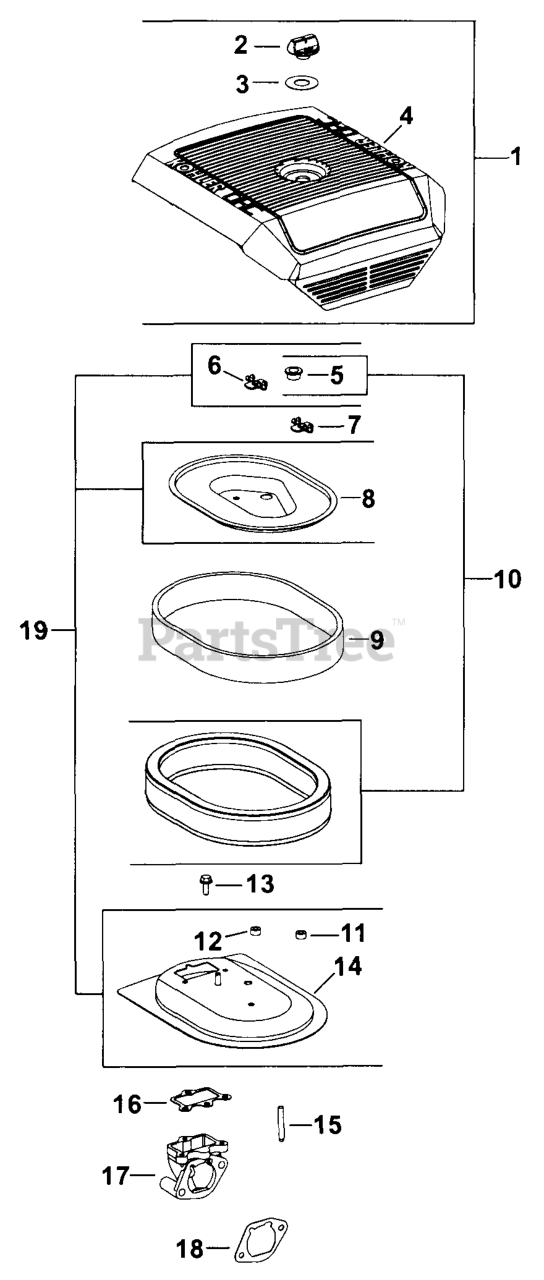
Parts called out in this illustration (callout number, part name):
1	KIT, AIR CLEANER COVER - (#DSC)
2	KNOB, COVER
3	GASKET, AIR CLEANER COVER KNOB
4	Cover, air cleaner
5	SEAL, CARB ADJUST SCREW
6	NUT, WING - (#DSC)
7	NUT, WING
8	COVER, INNER AIR CLEANER - DISCONTINUED
9	ELEMENT, PRE-CLEANER
10	ELEMENT KIT, AIR FILTER
11	SEAL, INNER AIR CLEANER
12	SEAL - DISCONTINUED
13	SCREW,FLG THD FRM M6X1.0X16-(#25086397S)
14	BASE, AIR CLEANER - (#DSC)
15	STUD - DISCONTINUED
16	GASKET, AIR CLEANR BASE
17	ELBOW, AIR CLEANER
18	GASKET, AIR CLEANER BASE
